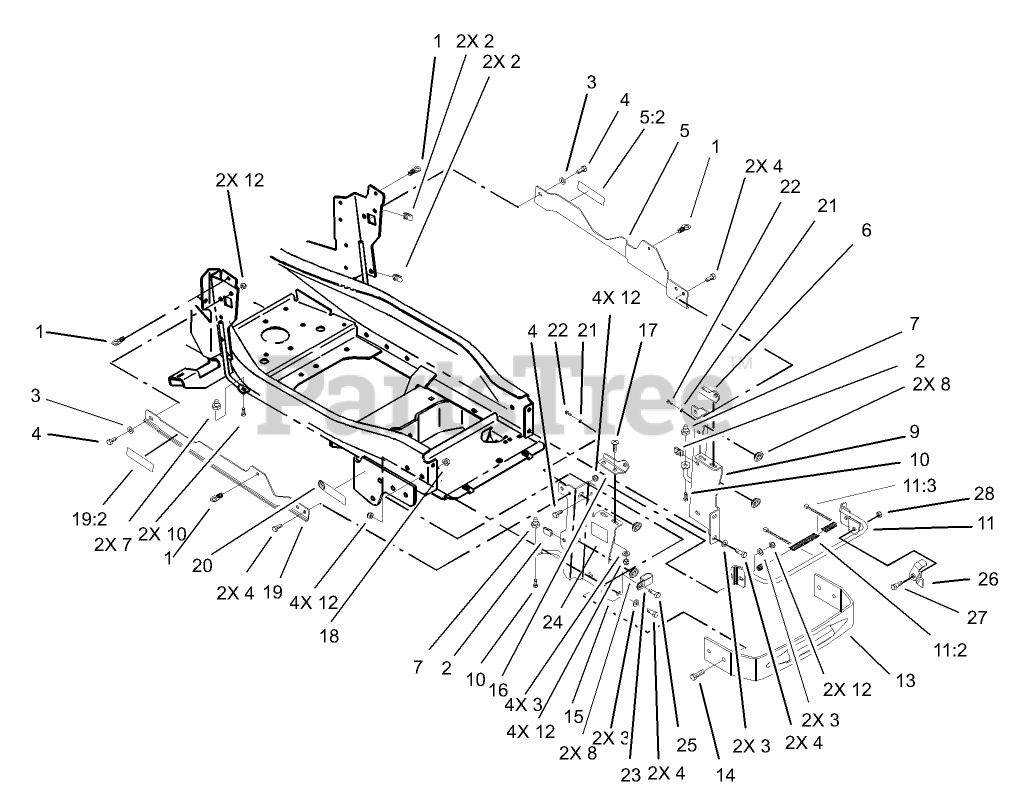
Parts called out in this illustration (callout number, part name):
1	LATCH ASM
3	WASHER-PLAIN
4	SCREW-HH
5	SUPPORT ASM
5:2	DECAL - WARNING
6	BRACKET-HINGE, LOWER LH
7	MOUNT-SIDEPANEL
8	GROMMET
10	SCREW-PLASTITE
11:2	COVER-BRACE
11:3	TIE-CABLE
12	NUT-LOCK, NI
14	SCREW-HH
15	SUPPORT-HOOD, RH
16	BRACKET-HINGE, LOWER RH
17	SCREW-CARR
18	NUT-LOCK, NI
19:2	DECAL - WARNING
20	DECAL-ATTACH A-MATIC
21	WASHER-FLAT
22	SCREW-THD FORM, HWH
23	CLAMP-TUBE
24	DECAL-SURFACE, HOT
25	SCREW-HH
26	LEVER-PROP, HOOD
27	BOLT-SHOULDER,HFH
28	NUT-LOCK, NI
